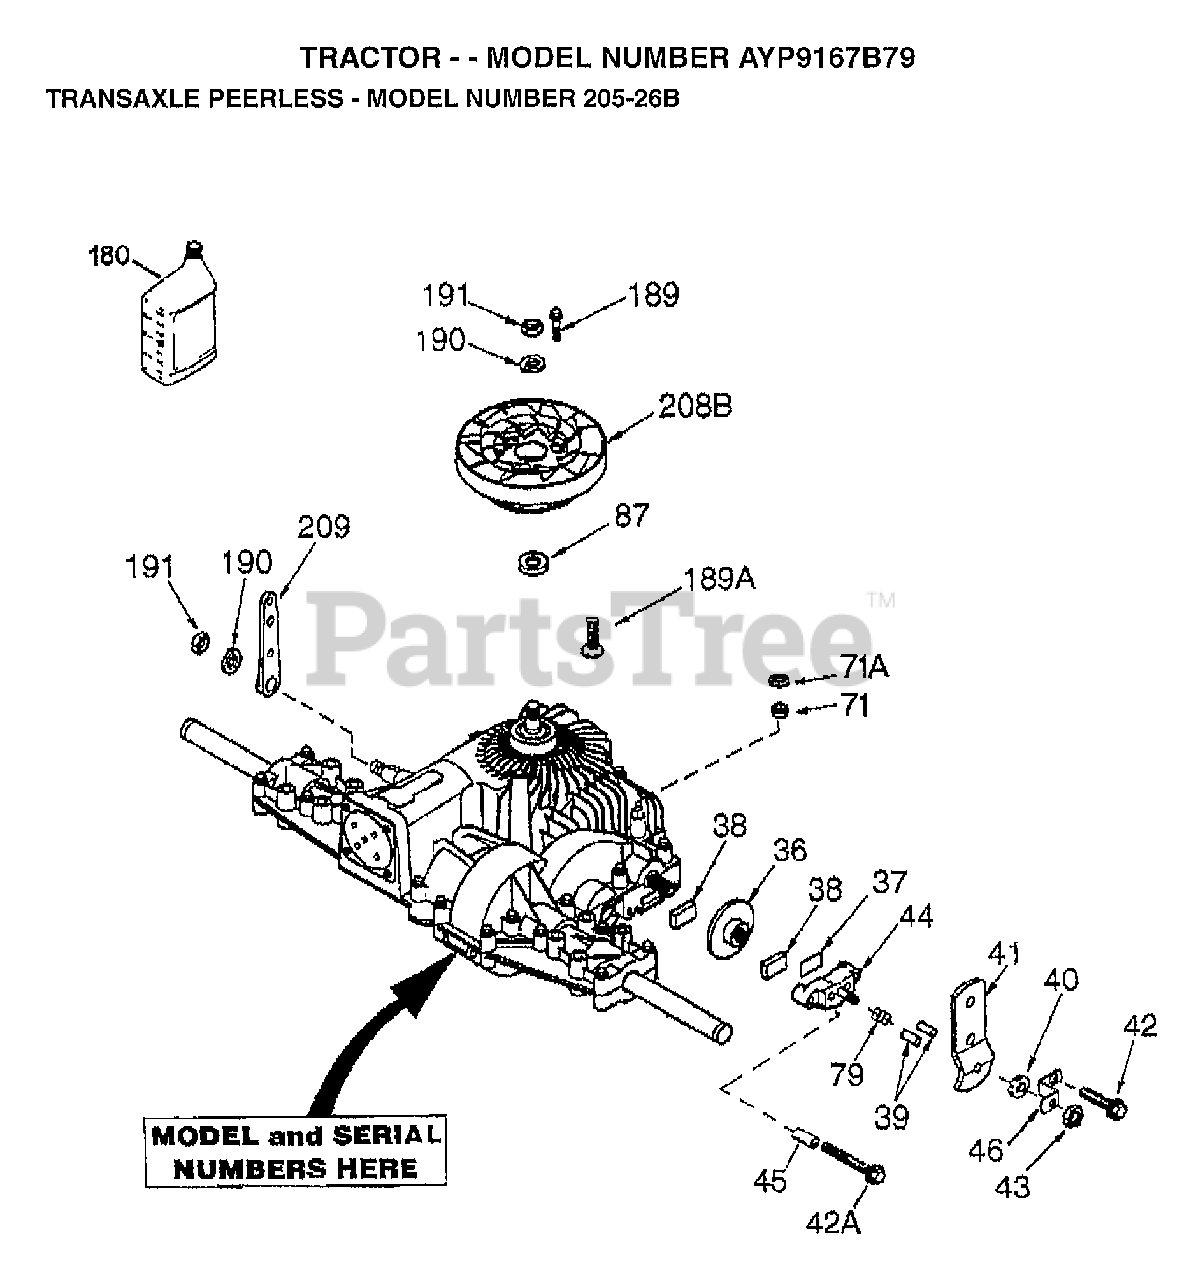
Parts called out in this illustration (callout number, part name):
37	PLATE BRAKE PAD
41	BRAKE LEVER
42	SCREW, 1/4-20 X 1-1/4
42A	SCREW, 1/4-20 X 2-1/4
43	LOCKNUT 5/16-24
44	HOLDER BRAKE PAD
46	BRAKE LEVER BRACKET
71	SEAL SQUARE CUT
180	GEAR OIL 80W90
189	DRIVE SCREW
208B	FAN/COUPLING
209	CONTROL LEVER
